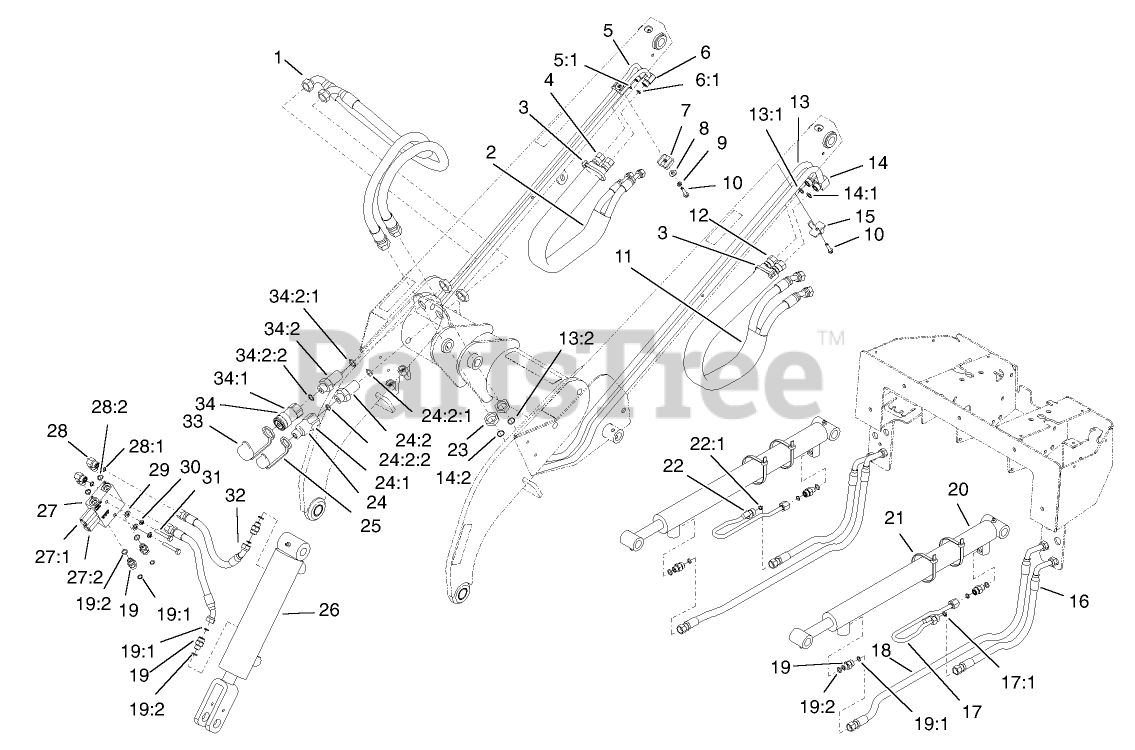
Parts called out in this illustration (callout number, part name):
1	HOSE ASM
2	SLEEVE-PROTECTIVE
3	TIE-CABLE
4	HOSE-HYD
5	HYD TUBE ASM
5:1	O-RING
6	HYD TUBE ASM
6:1	O-RING
7	CLAMP-TUBE
8	WASHER-FLAT
9	WASHER-LOCK
10	SCREW-HWH
11	SLEEVE-PROTECTIVE
12	HOSE-HYD
13	HYD TUBE ASM
13:1	O-RING
13:2	O-RING
14	HYD TUBE ASM
14:1	O-RING
14:2	O-RING
15	PLATE-CLAMP, TUBE
16	HOSE-HYD
17	HYD TUBE ASM
17:1	O-RING
18	HYD HOSE ASM
19	FITTING-STRAIGHT
19:1	O-RING
19:2	O-RING
20	CYLINDER-LIFT
21	TIE-CABLE
22	HYD TUBE ASM
22:1	O-RING
23	NUT-LOCK, BULKHEAD
24	BULKHEAD NIPPLE ASM
24:1	NIPPLE-FACE, FLUSH
24:2	FITTING-ADAPTER, BULKHEAD
24:2:1	O-RING
24:2:2	O-RING
25	CAP-DUST, NIPPLE
26	CYLINDER-TILT
27	VALVE-RELIEF, CROSSOVER
27:2	CARTRIDGE-RELIEF
27:3	CARTRIDGE-RELIEF
28	FITTING-ELBOW, 90 DEG
28:1	O-RING
28:2	O-RING
29	WASHER-PLAIN
30	WASHER-LOCK
31	SCREW-HH
32	HOSE-HYD
33	CAP-DUST, COUPLER
34	BULKHEAD COUPLER ASM
34:1	COUPLER-FACE, FLUSH
34:2	FITTING-ADAPTER, BULKHEAD
34:2:1	O-RING
34:2:2	O-RING
